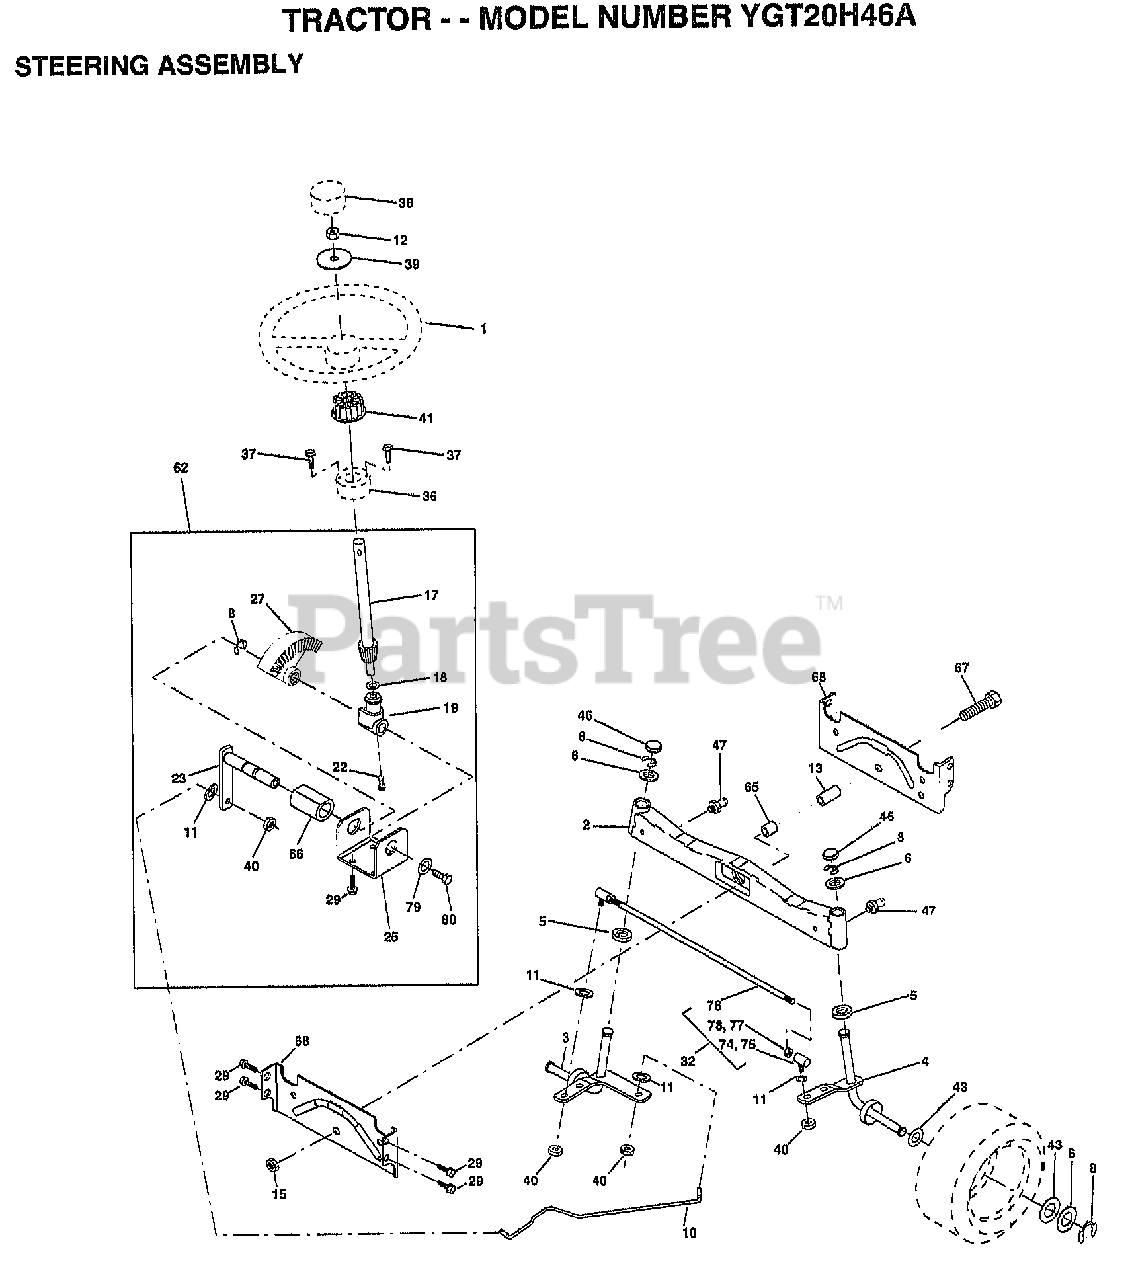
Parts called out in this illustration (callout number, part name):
3	"SPINDLE ASM,RH"
4	"SPINDLE ASM,RH"
5	WASHER .T
6	WASHER
8	RING
10	LINK.DRAG
11	LOCKWASHER
13	BEARING AXLE
15	"NUT-LOC,FLANGE LT"
17	STEERING SHAFT
18	THRUST WASHER
19	SUPPORT.SHAFT.STEER
22	SCREW.HX.WSH.HD
23	SHAFT.ASM.PITMAN
25	BRKT-STEERING
27	GEAR SECTOR
29	SCREW
32	ROD.ASM.TIE.BALL
36	BUSHING.STRG.3/4
37	"SCREW-TT,10-32 FL"
38	"INSERT,STR WHEEL"
39	WASHER
40	GRIPCO NUT
41	ADAPTER LT
43	WASHER
46	CAP
47	ZERK M
62	KIT.STEER.ASM
65	SPACER AXLE
66	"BEARING-ARM,PITMA"
67	BOLT
68	BRACE AXLE
74	JOINT ASM BALL
75	JOINT ASM BALL
77	NUT
78	NUT
79	WASHER
80	BOLT.HX.NYLON3/8-16X3/
